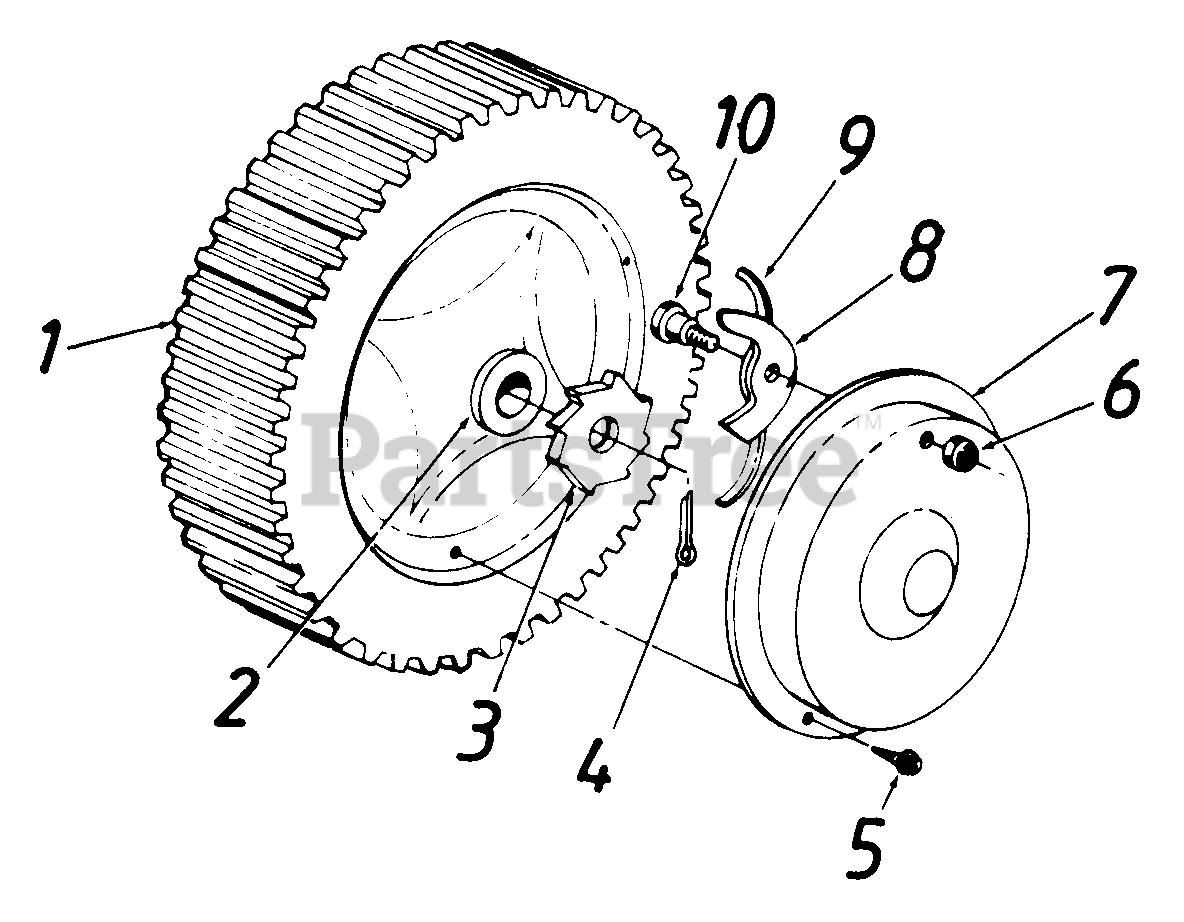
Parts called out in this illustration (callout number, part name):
1	Rear Wheel Assembly
2	Flange Ball Bearing 1/2" I.D.
3	Ratchet Wheel 1.63 O.D.
4	Cotter Pin 1/8" Dia. x 1.00" Lg.
5	Pan Hd. Tap Scr. #12 x .50" Lg.
6	Hex Ins. L-Nut 1/4-20 Thd.
7	Hub Cap
8	Pawl
9	Spring-Nylon
10	Shld. Scr..342" Dia. x .268
